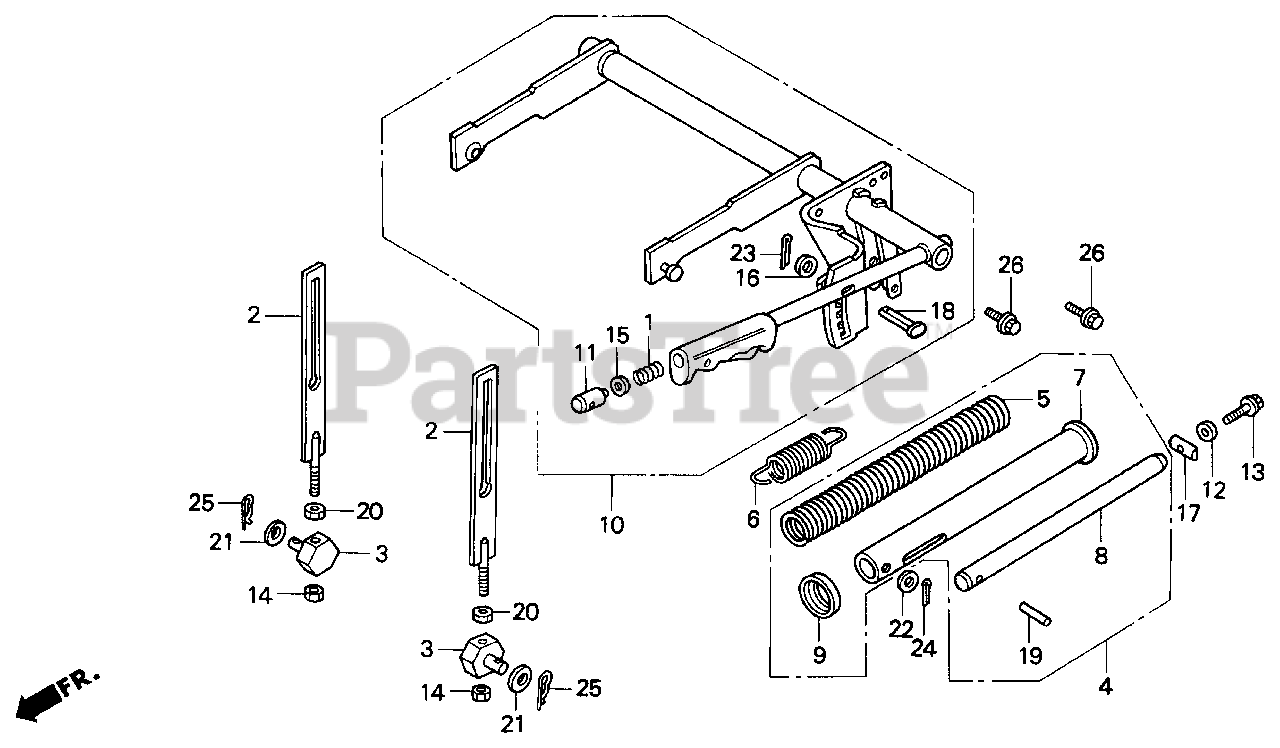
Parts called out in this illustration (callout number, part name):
1	SPRING, PUSH ROD
2	ROD, CUTTER DECK LIFT
3	PIN, RR. LINK ADJUSTING
4	PIPE ASSY., COUNTER SPRING
5	SPRING, DECK LIFT
6	SPRING, DECK LIFT SUB
7	PIPE (OUTER)
8	PIPE (INNER)
9	WASHER, SPRING GUIDE
10	LEVER ASSY., HEIGHT ADJUSTING *NH105* (MAT BLACK)
11	KNOB, PUSH ROD *NH105* (MAT BLACK)
12	WASHER, PLAIN
13	BOLT (8X100)
14	NUT, SELF-LOCK (10MM)
15	WASHER (11MM)
16	WASHER, PLAIN (9MM)
17	PIN (14X40)
18	PIN, HEIGHT ADJUSTING LEVER
19	ROLLER (6X49)
20	NUT, HEX. (10MM)
21	WASHER, PLAIN (10MM)
22	WASHER, FLAT (12MM)
23	PIN, COTTER (2.0X15)
24	PIN, COTTER (2.0X22)
24	PIN, COTTER (2.0X35)
25	PIN, LOCK (10MM)
26	BOLT, FLANGE (8X20)
